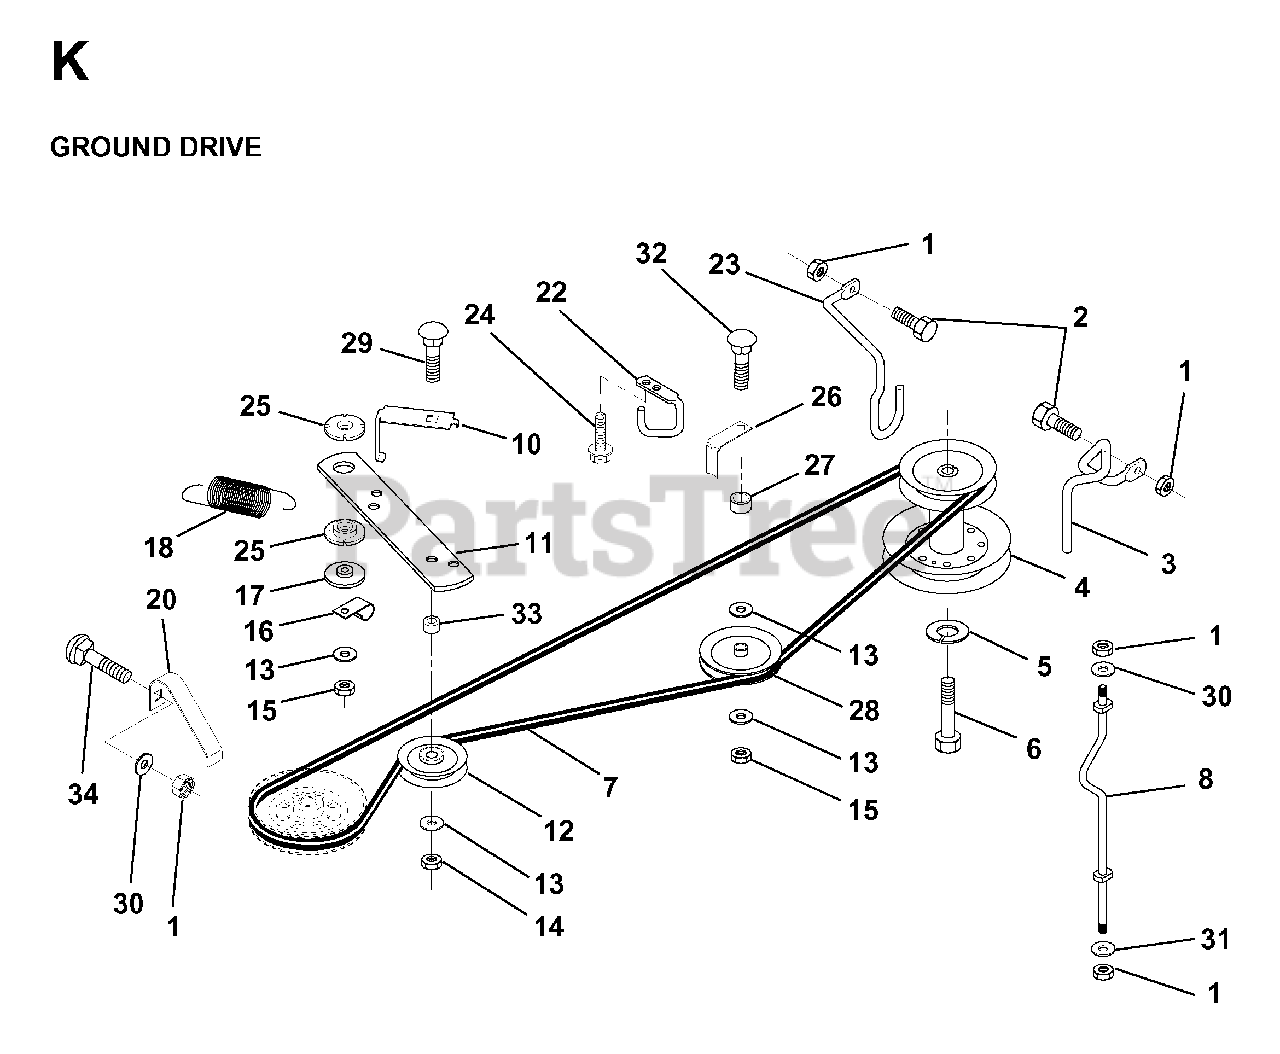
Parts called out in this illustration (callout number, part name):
1	NUT.71038.31-18.HEX.NYLOCK
2	BOLT
4	ENGINE PULLEY
5	LOCKWASHER
10	KEEPER, BELT
11	ARM, GROUND DRIVE CLUTCH
12	PULLEY.IDLER.FLAT
14	LOCKNUT
15	LOCKNUT
16	CLIP,INSULATOR
17	SPACER, RETAINER
18	SPRING.EXTENSION
20	KEEPER, BELT
22	KEEPER,FRA DR BEL
23	KEEPER-MOWER DRIVE LH
24	SCREW
25	BUSHING NYLON COLLERED
26	KEEPER, BELT
28	PULLEY.IDLER.V.
29	BOLT
30	WASHER
31	WASHER M
32	BOLT
33	SPACER NLA
34	BOLT
